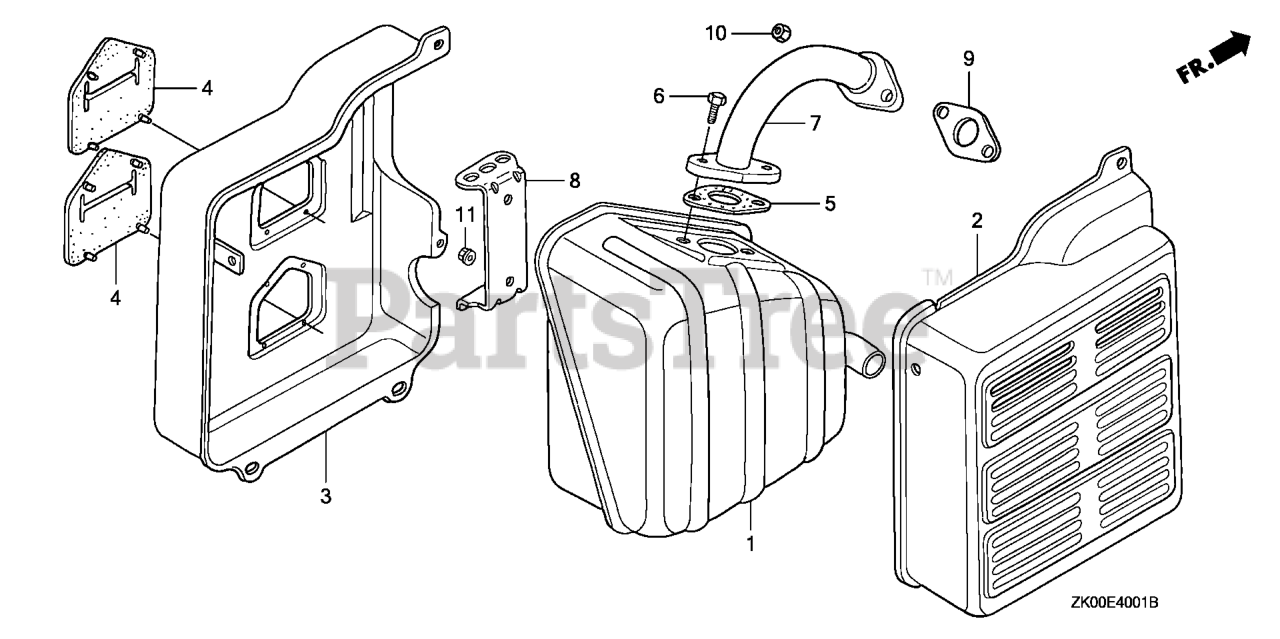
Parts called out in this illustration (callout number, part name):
1	MUFFLER
2	PROTECTOR, MUFFLER (OUTER)
3	PROTECTOR, MUFFLER (INNER) (DENYO)
4	SEAL, MUFFLER PROTECTOR
5	GASKET, MUFFLER
6	BOLT, HEX. (8X20)
